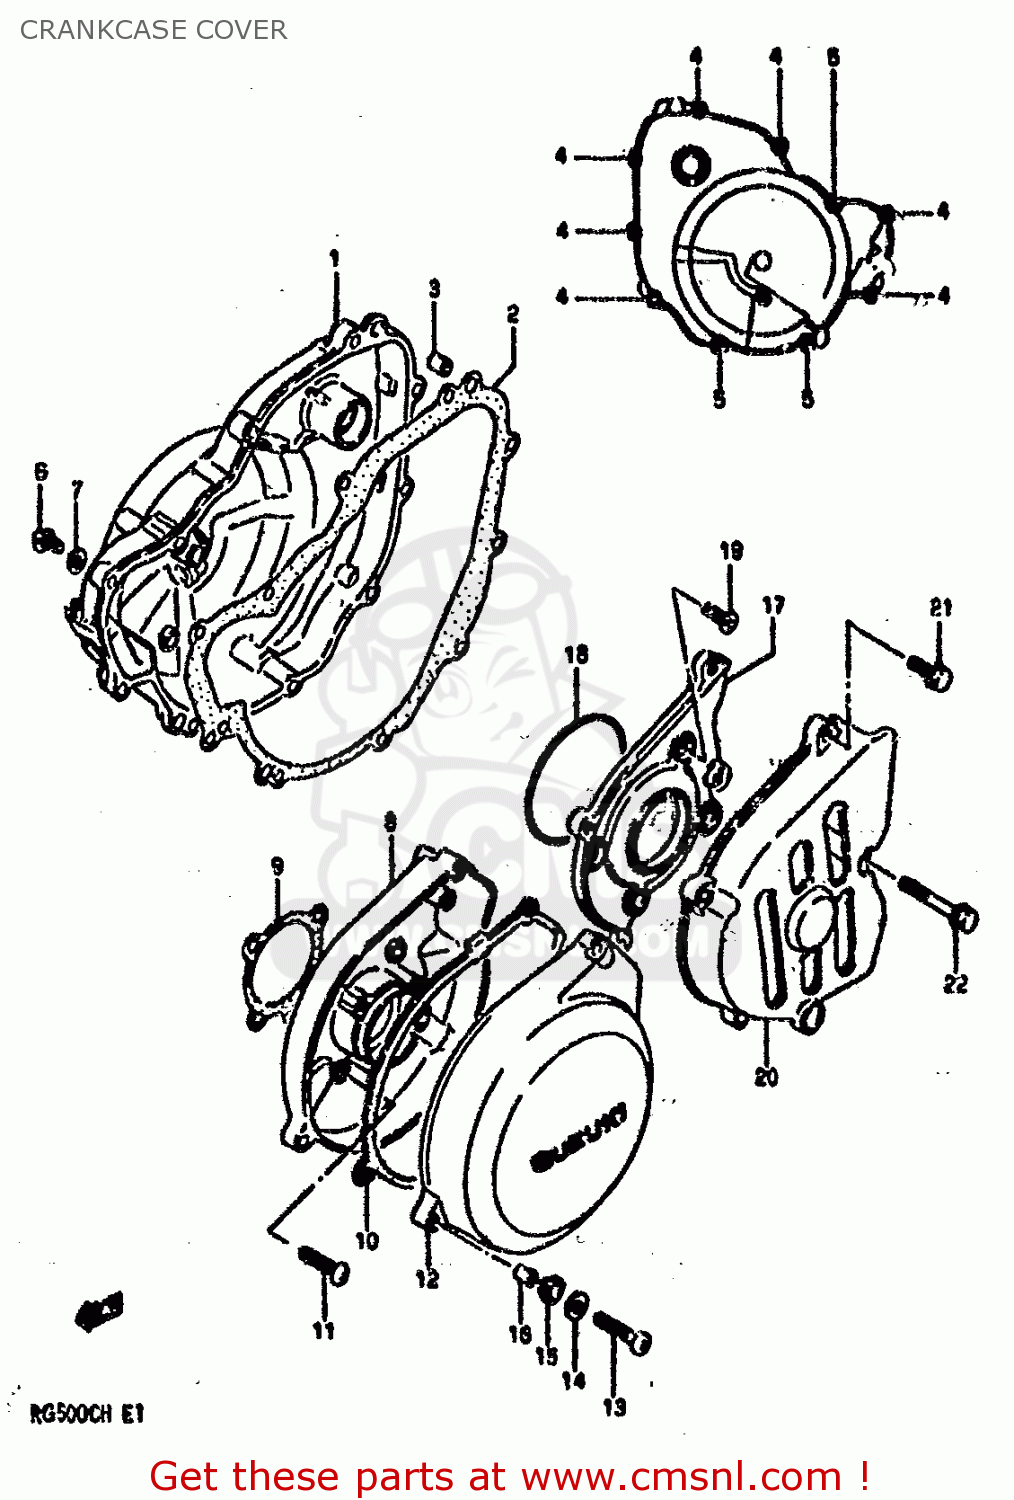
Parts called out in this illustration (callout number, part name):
1	COVER,CLUTCH
2	GASKET,CLUTCH COVER
3	PIN
4	BOLT 6X25
5	BOLT 6X35
6	SCREW (6X10)
7	GASKET(6.2X11X1).2 (NAS)
8	COVER,MAGNETO INNER
9	GASKET,MAGNETO COVER (MCA)
10	CUSHION,MAGNETO COVER
11	SCREW
12	COVER,MAGNETO OUTER
13	SCREW
14	WASHER
15	WASHER
16	SPACER
17	COVER,SPROCKET INNER
18	O RING(D:2.4,ID:76.8)
19	SCREW
20	COVER,SPROCKET OUTER
21	BOLT 6X20
22	BOLT
